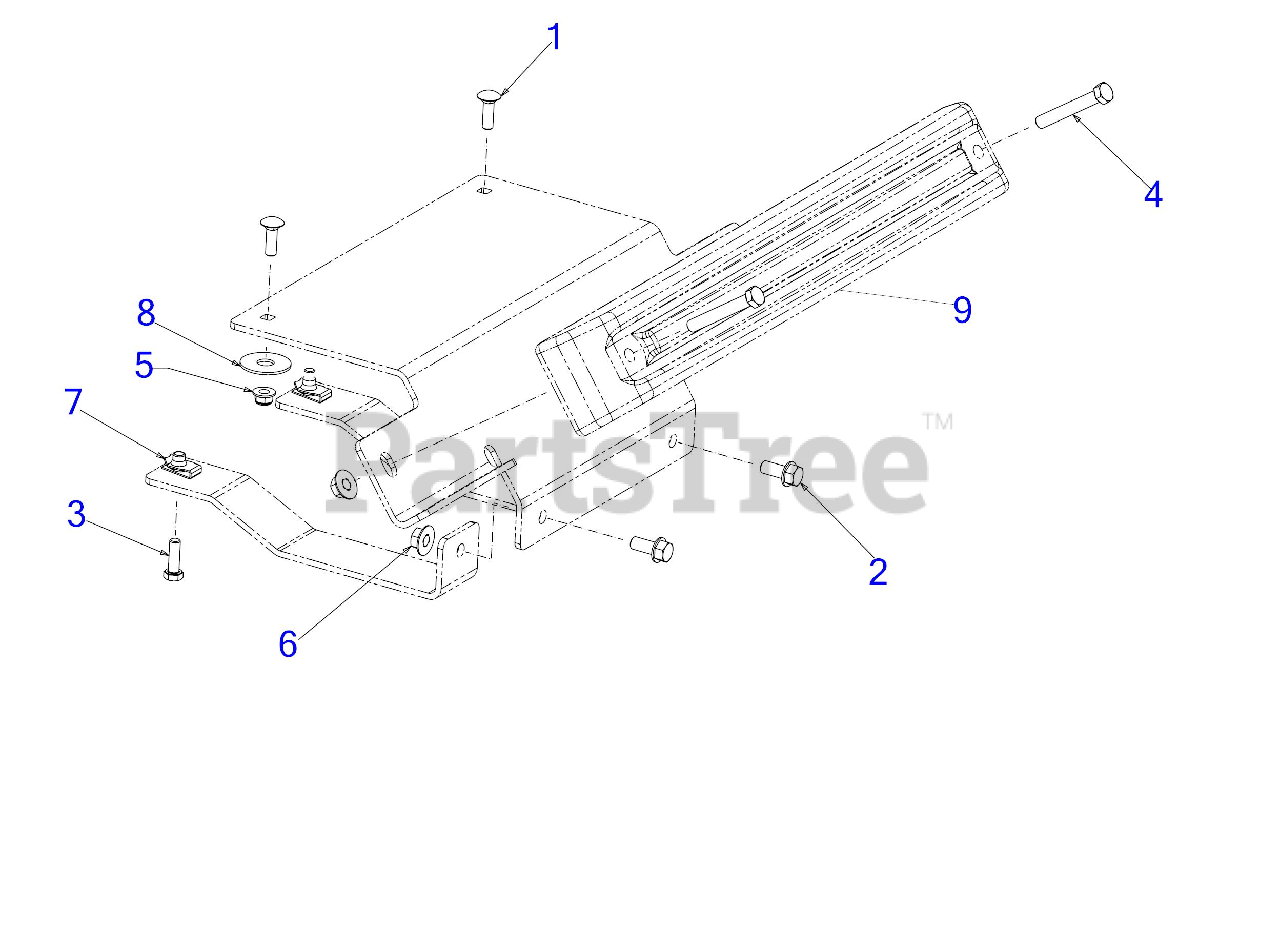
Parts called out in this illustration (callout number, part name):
1	CARRIAGE BOLT 5/16-18 x 1.00
2	SCREW 3/8-16 x .875 GR5
3	SCREW 5/16-18 x 1.00 GR5
4	HEX SCREW-3/8-16X2.5 GR5
5	FLANGE LOCK NUT 5/16-18
6	FLANGE LOCK NUT
7	U-NUT
8	WASHER .51 x 1.5 x .07
9	BAGGER WEIGHT
